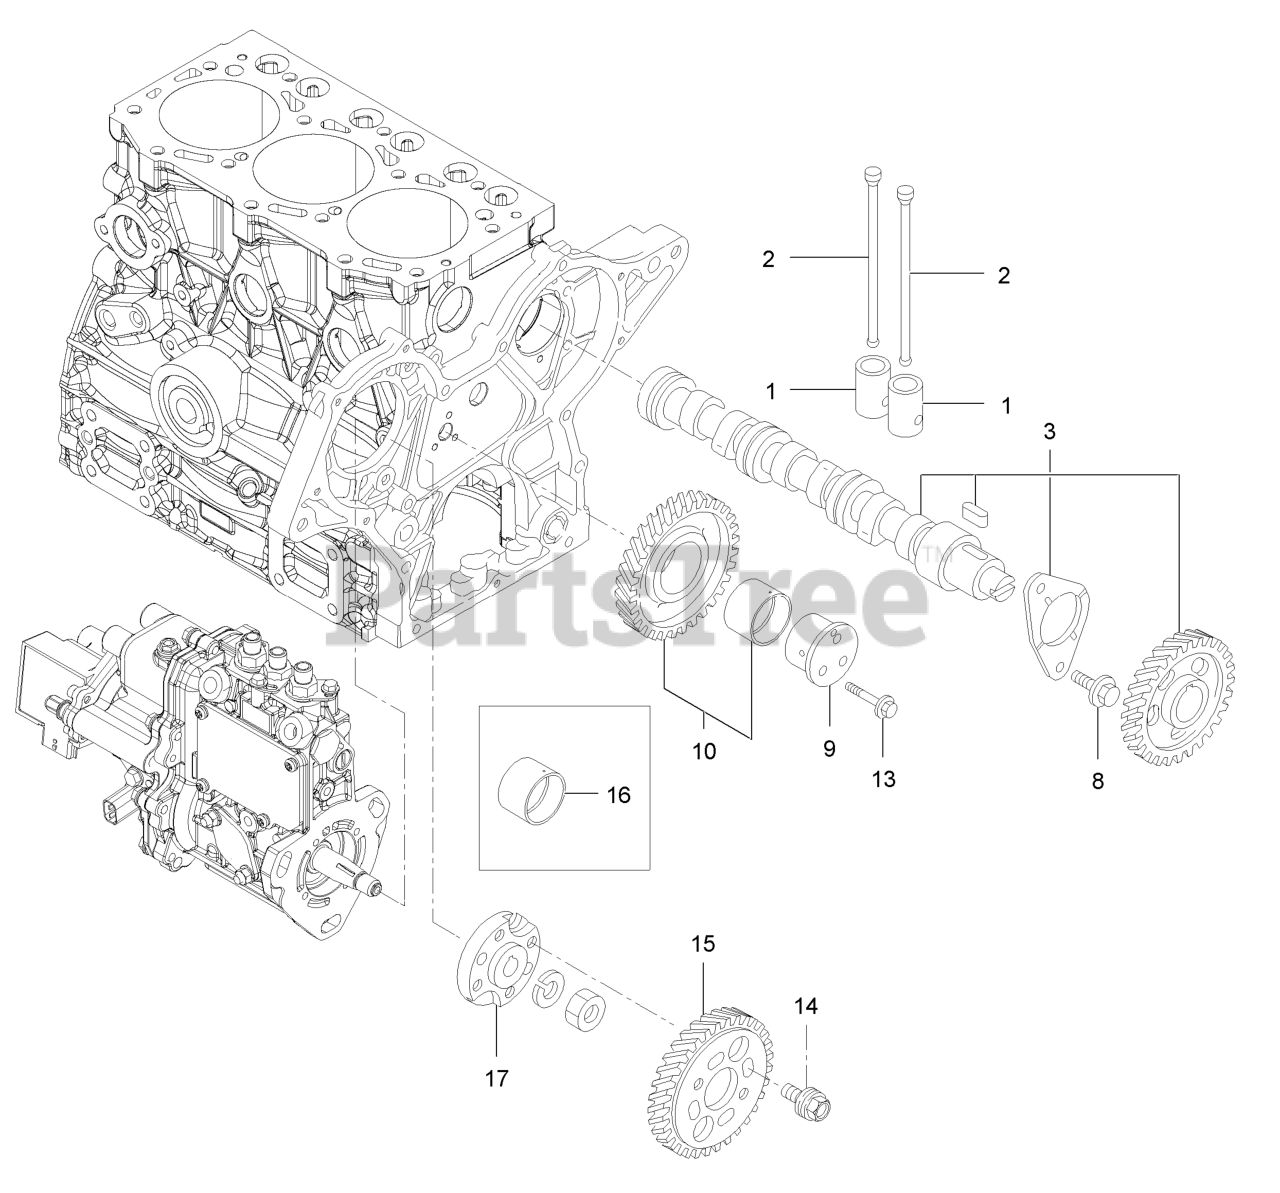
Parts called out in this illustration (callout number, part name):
2	Push-Rod
3	Camshaft ASM
9	Shaft-Idle
10	Gear Assy-Idle
15	Gear-Pump
16	Bush-Idle Gear
